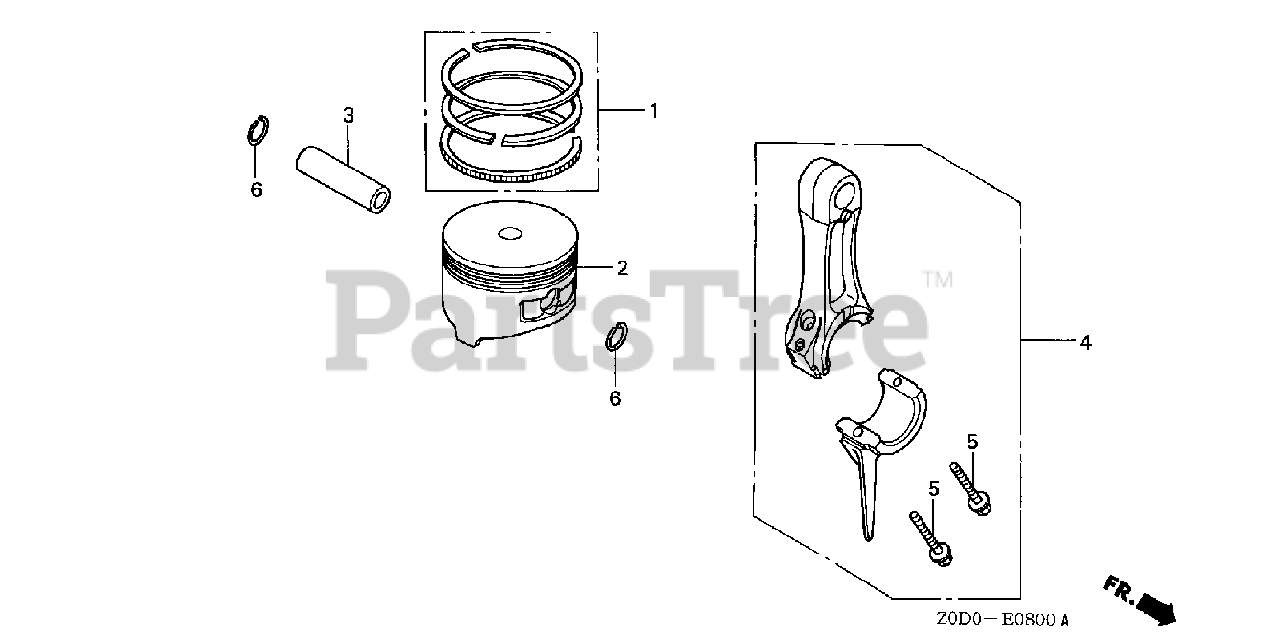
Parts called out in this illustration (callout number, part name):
1	RING SET, PISTON
2	PISTON
3	PIN, PISTON
4	ROD ASSY., CONNECTING
5	BOLT, CONNECTING ROD
6	CLIP, PISTON PIN (13MM)
